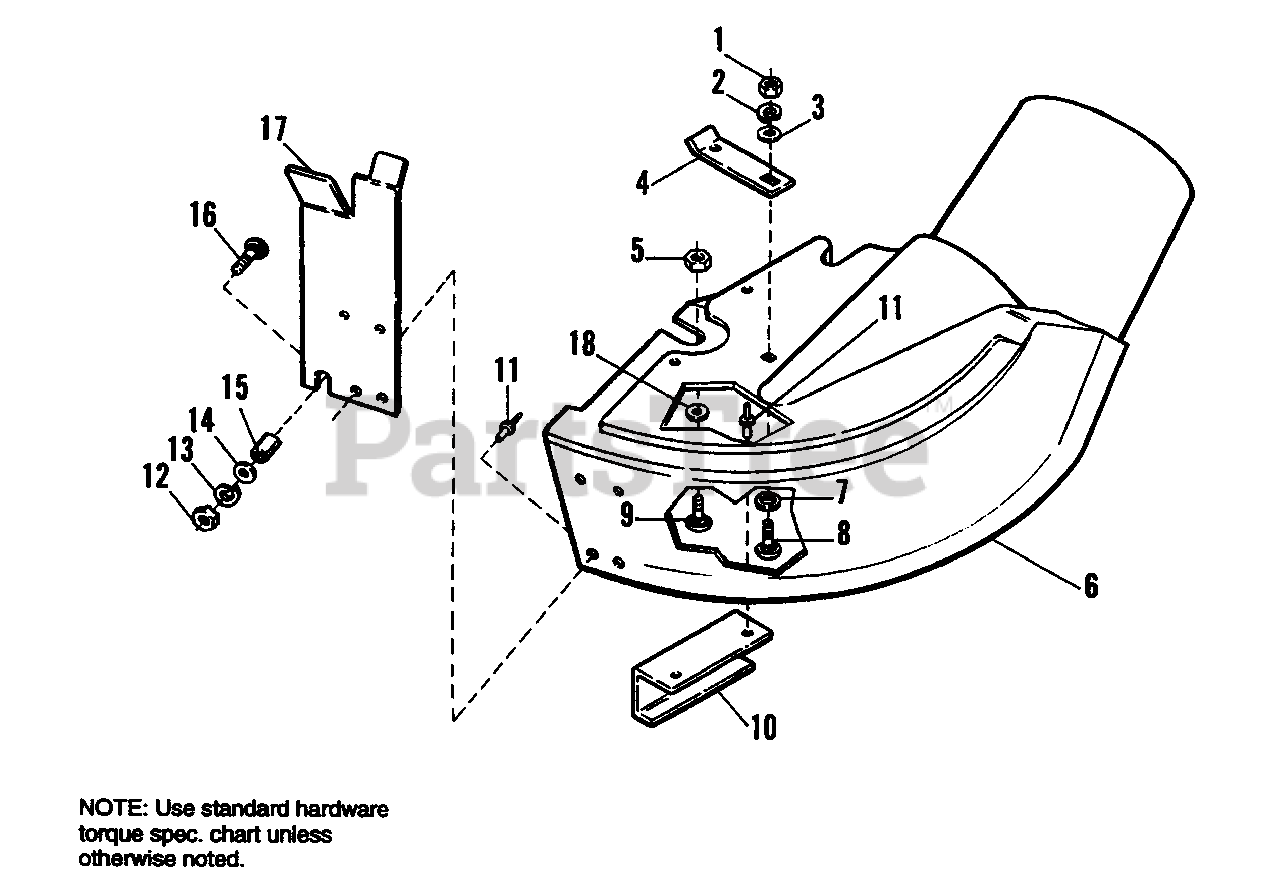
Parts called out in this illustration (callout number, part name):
1	NUT, Hex, 5/16-18 UNC, 2B
2	LOCKWASHER, 5/16, Helical Spring
3	WASHER, Plain, 3/8 x 7/8
4	LATCH, Spring
5	NUT, Hex, Centerlock, Jam, 3/8-16 UNC
6	ADAPTOR ASSY.
7	WASHER, Plain, 7/16 x1
8	BOLT, Rd. Hd., 5/16-18 UNC x
9	BOLT, Rd. Hd., 3/8-16 UNC x 7/8
10	ADAPTOR, Hold Down
11	RIVET, Oval Hd., 3/16 x 5/16
12	NUT, Hex, 3/8-16 UNC
13	LOCKWASHER, 3/8 Helical Spring
14	WASHER, Plain, 3/8 x 1-1/4 X 1/8
16	BOLT, Rd. Hd., 3/8-16 UNC x 1
17	DEFLECTOR BRACE ASSY.
18	WASHER, Plain, 1/2 x 7/8
